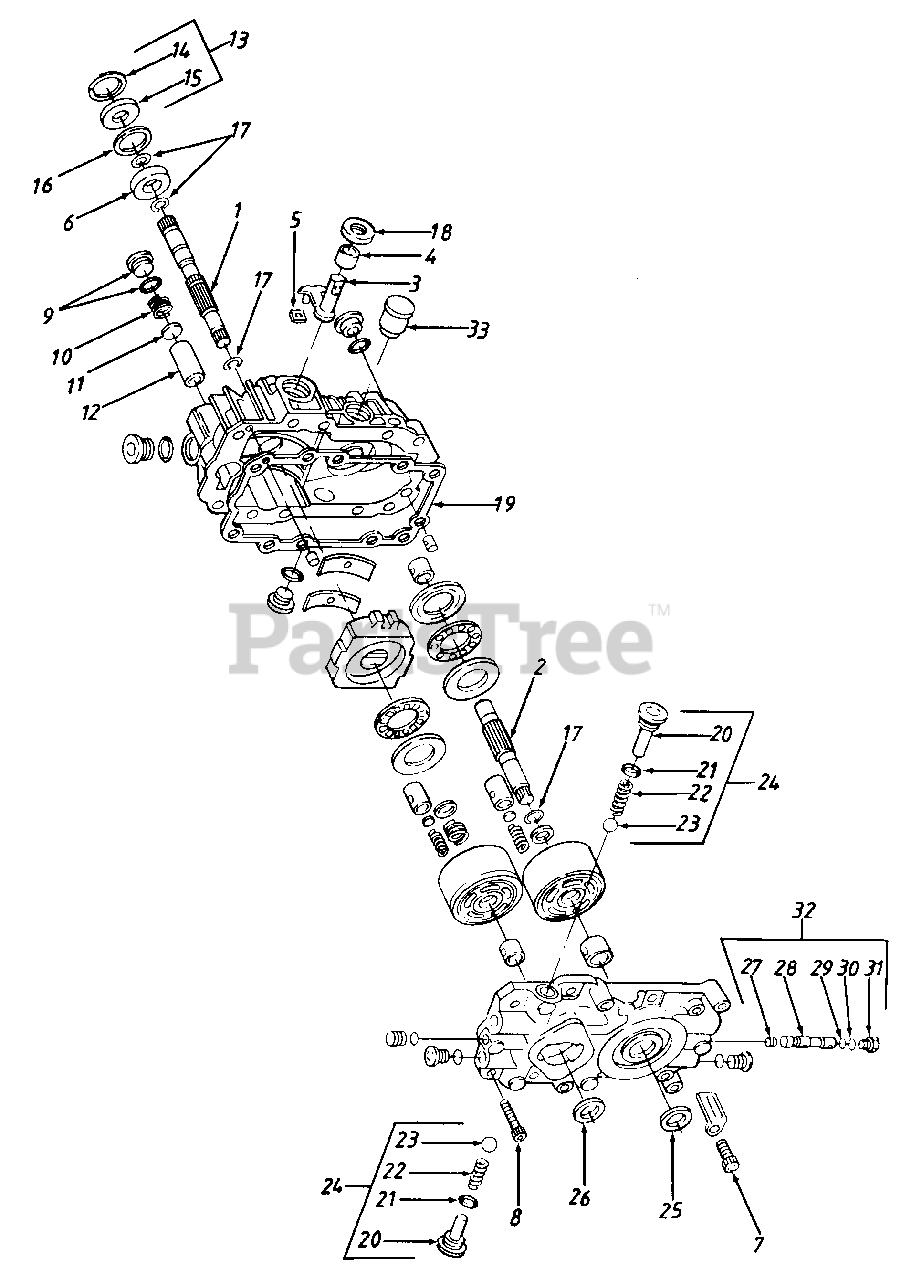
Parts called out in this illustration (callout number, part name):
1	Shaft-Pump
2	Shaft-Motor
3	Arm, Trunnion
4	Bearing, Journal
5	Guide, Slot
6	Bearing, Ball
7	Screw, Socket Head
8	Screw, Socket Head
9	Plug
10	Spring, Filter
11	Washer, Filter
12	Filter
13	Kit, Seal
14	Ring, Retaining
15	Seal, Lip
16	Spacer
17	Ring, Retaining
18	Seal, Lip
19	Gasket
21	O-Ring
24	Kit, Check Valve
25	Seal, Lip
26	Seal, Lip
27	Spring
28	Spool, Bypass
29	O-Ring
30	O-Ring
32	Kit, Bypass Valve
33	Reservoir
